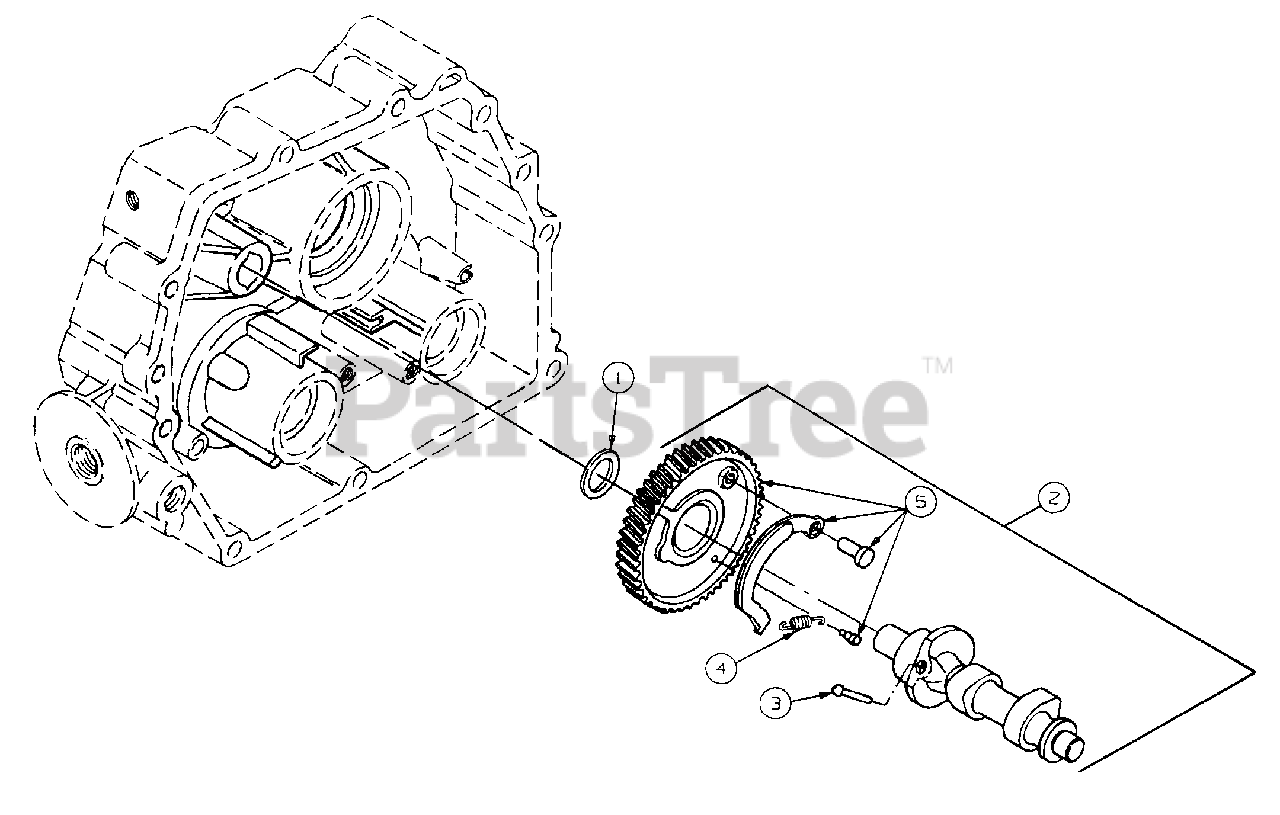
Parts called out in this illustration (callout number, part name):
1	Shim, Camshaft, 0.5 mm
2	Camshaft Assy
3	Pin, Decompression
4	Spring, Decompression
5	Camgear Assy
